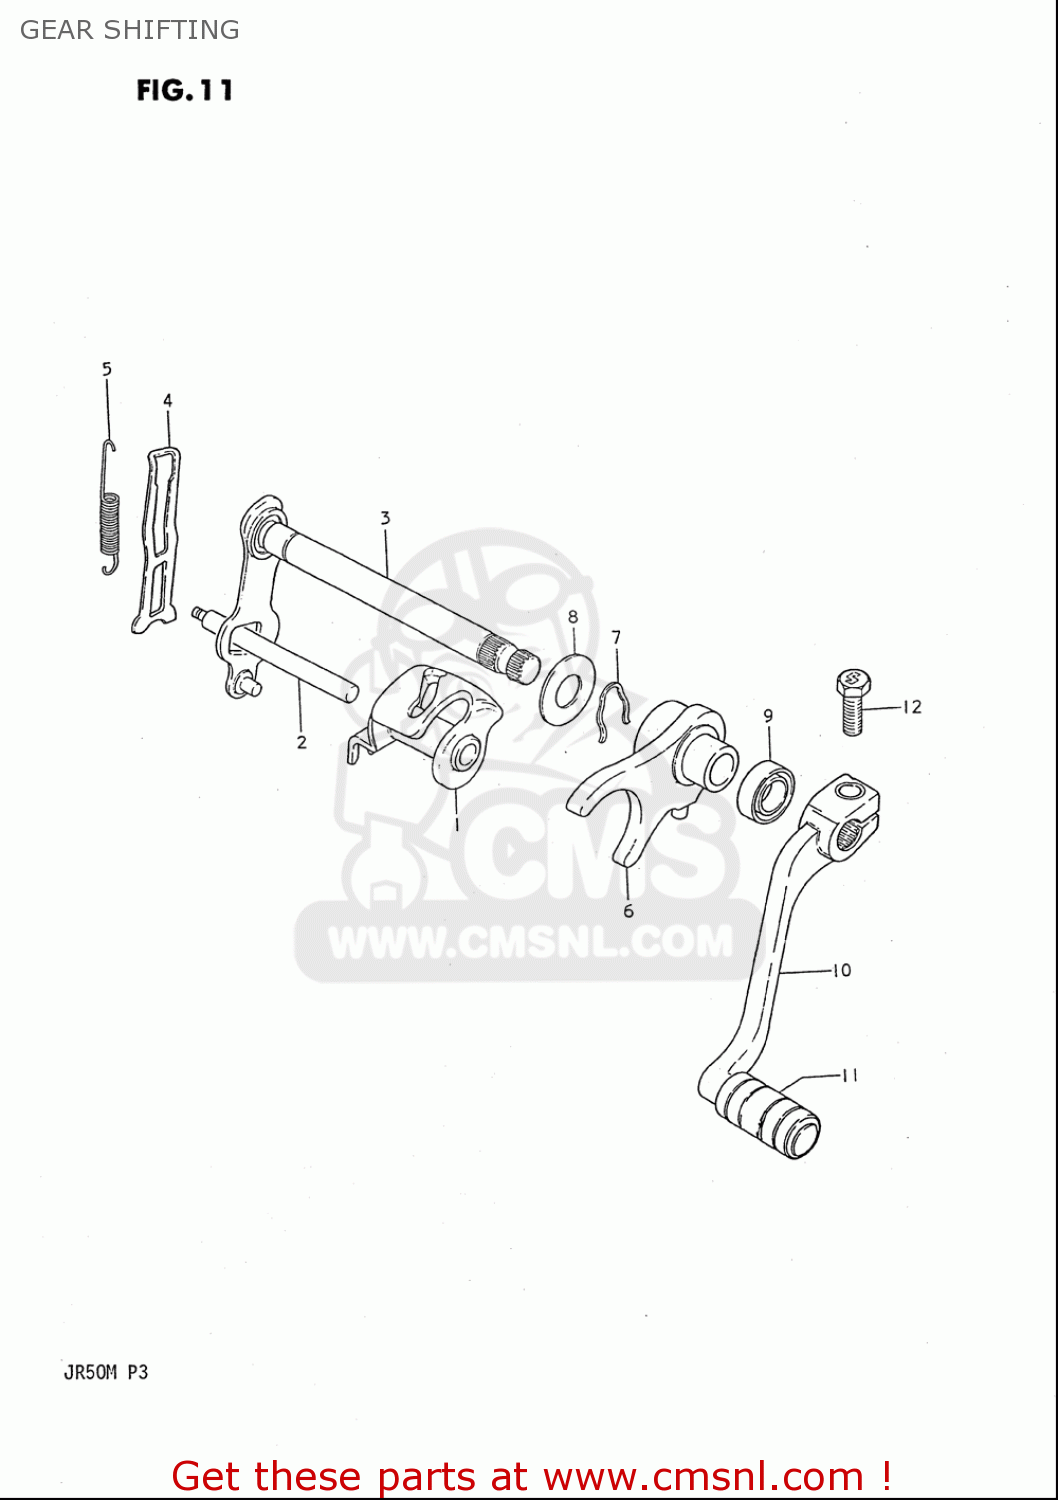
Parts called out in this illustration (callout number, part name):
1	CAM,GEAR SHIFT
2	SHAFT,GEAR SHIFT CAM
3	SHAFT,GEAR SHIFT
4	ARM,GEAR SHIFT CAM STOPPER
5	SPRING
6	FORK,GEAR SHIFT
7	CIRCLIP,12 MM
8	WASHER
9	SEAL,OIL (12X22X9)
10	LEVER ASSY,GEAR SHIFT
11	RUBBER,GEAR SHIFT PEDAL
12	BOLT
